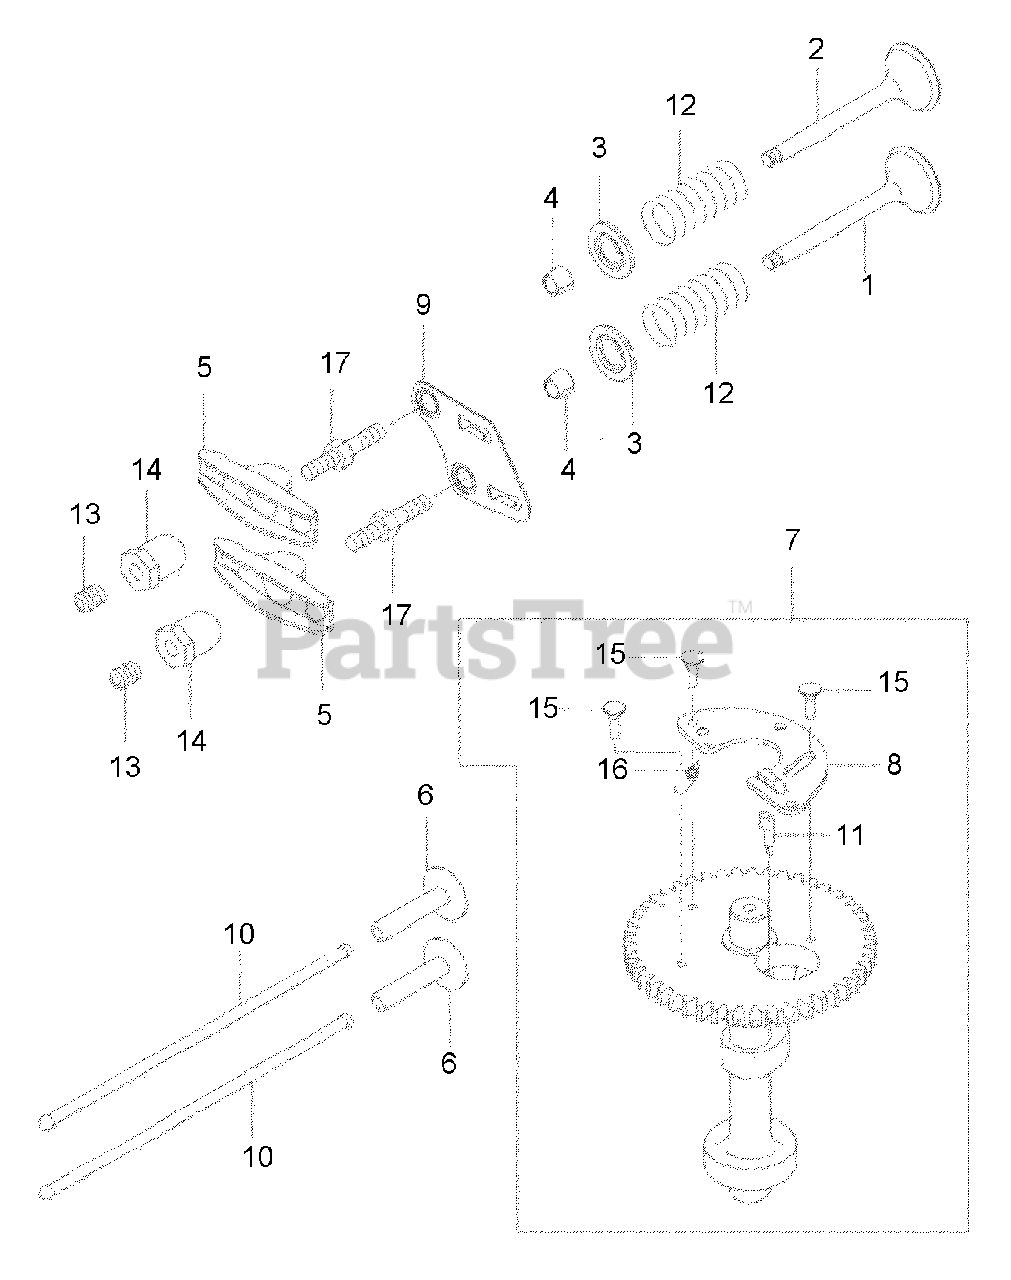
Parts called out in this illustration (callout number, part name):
1	Intake Valve
2	Exhaust Valve
3	Valve Spring Retainer
5	Rocker Arm
7	Camshaft Assy.
10	Push Rod
